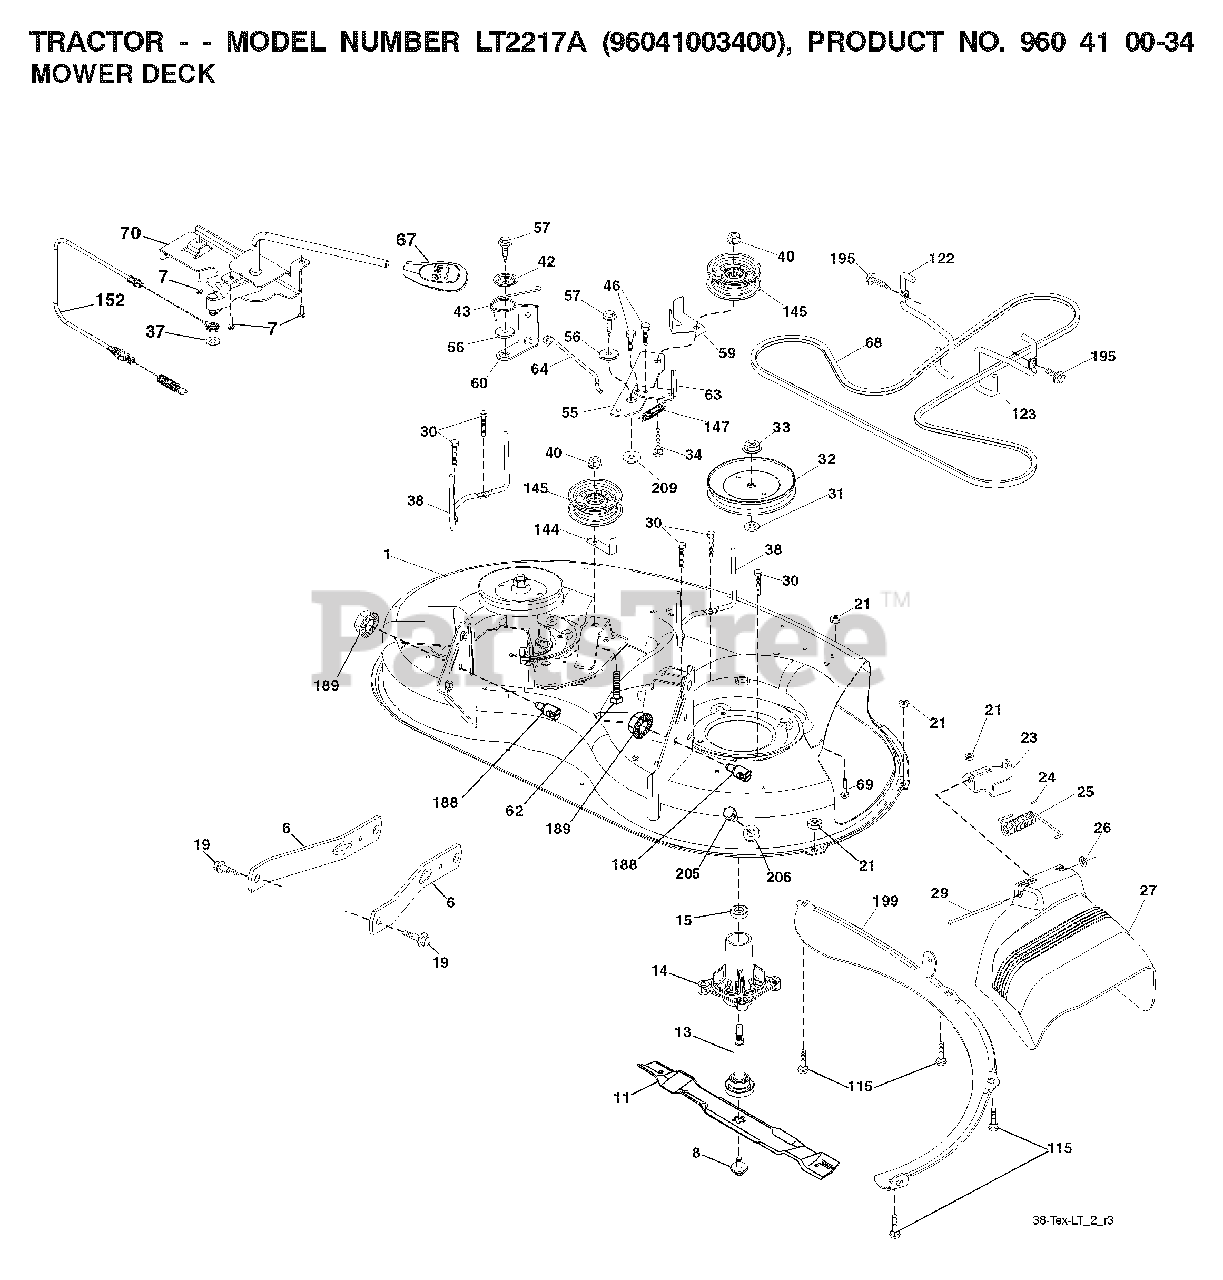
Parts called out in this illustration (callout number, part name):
6	ARM.SUSPENSION.MOWER.R
7	SCREW.#10 X 0.750.BOS THREAD
8	BOLT.WASHER.ASM.7/16-2
11	BLADE 38" PREMIUM
14	HOUSING MANDREL
19	BOLT.SHOULDER
21	LOCKNUT
23	BRKT.DEFLECTOR.38"2005+
24	CAP-SLEEVE LT
25	SPRING.TORSION.DEFLECT
26	NUT PUSH M
29	ROD.HINGE
30	SCREW, WASHER HEAD
31	WASHER.SPACER.MANDREL
32	PULLEY.MANDREL.5.0.PD.38"
33	NUT.FLANGE.LOCK.TOP
34	BOLT.3/8-16X1.50
38	KEEPER BELT LH MANDREL
40	NUT LOCK FLG 3/8-16 UNC
42	SPRING.TORSION.BRAKE
43	SRPING.TORSION.RETAINE
46	SCREW.1/4-20X5/8
55	IDLER.ARM
56	SPACER.RETAINER
57	SCREW 3/8-16X1
59	GUARD, BELT
60	ARM BRAKE MOWER RH 38"
62	BOLT.3/8-16X1.50
63	ARM BRAKE MOWER RH
64	LINK BRAKE
67	HANDLE.CLUTCH.CABLE.LT
69	BOLT
70	CLUTCH.ASM.MANUAL.LT.TEX
115	BOLT
122	KEEPER BELT ENGINE LH
123	KEEPER BELT RH
144	KEEPER, BELT IDLER
145	PULLEY.IDLER.48"PRIMARY
147	SPRING RETURN
152	CLUTCH CABLE
188	STUD.FASTNER.W/ANTI-ROTATE
189	NUT LOCK HEX FLANGE 5/16-18
195	SCREW, 3/8-16X3/4
199	BAFFLE VORTEX
205	SCREW
208	SCREW 3/8-16X1/2
209	WASHER 12/32X2X10GA
